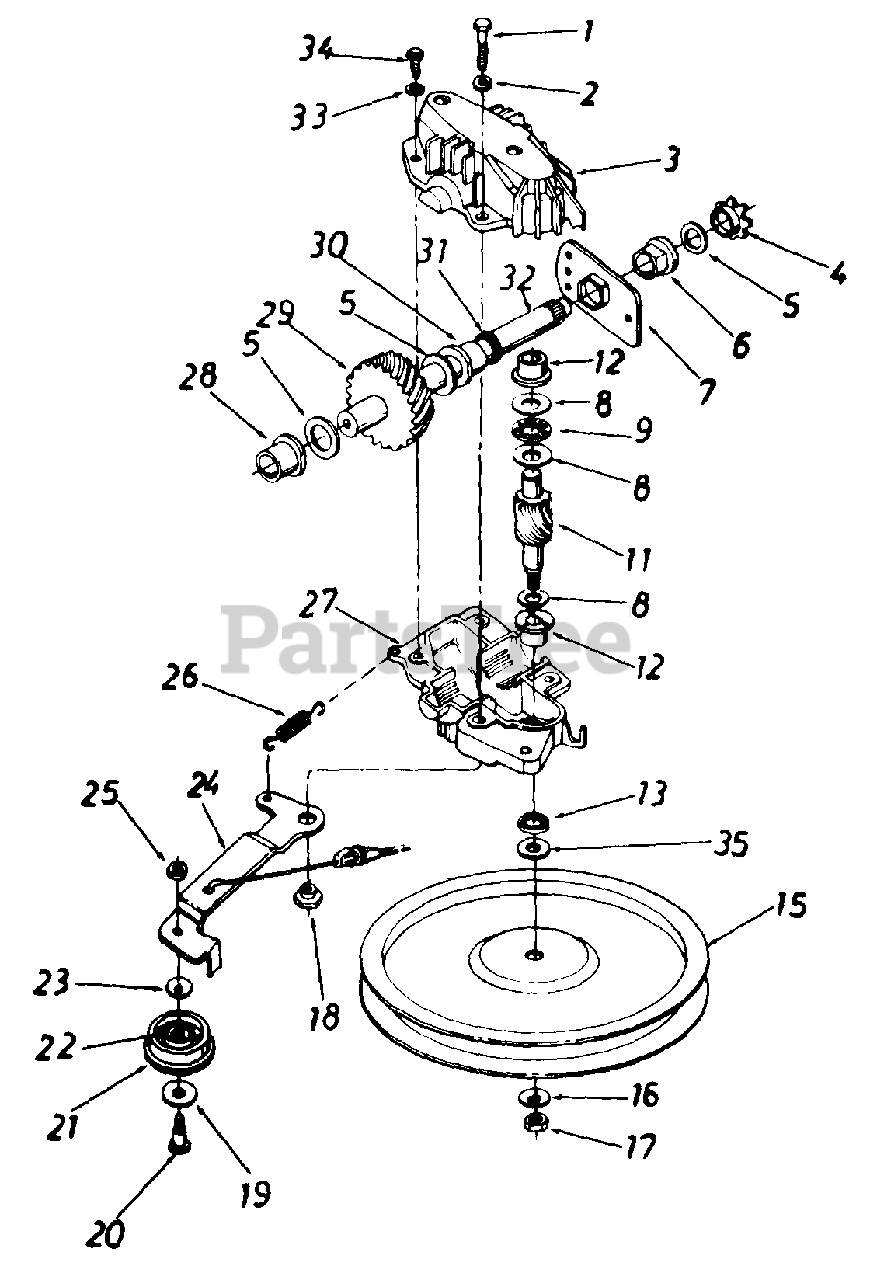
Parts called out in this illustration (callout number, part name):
1	Hex Bolt 1/4-20 x 1.25" Lg. w/Patch
2	L-Wash. 1/4" l.D.
3	Upper Hsg. Half
4	#48 Sprocket 7 Tooth x 1/2 Pitch
5	Fl-Wash. 5/8" I.D. x .030
6	Hex Flange Brg. .631" I.D.
8	Thrust Wash. .382" I.D. x .70" O.D.
9	Thrust Bearing .375" I.D. x .812" O.D.
11	11 Tooth Pinion Shaft
12	Flange Bearing
15	Fl-Pulley 5.06" O.D.
16	Bell-Wash. .265" I.D. x .75"
17	Hex L-Nut 1/4-28 L.H. Thd.
18	Shld. Spacer .375" Dia. x .170
19	Fl-Wash. .390" I.D. x 1.0"
20	Shld. Bolt .375" Dia. x .40"
21	Fl-Idler Plastic 1.50" Dia.
22	Needle Brg. .375" x .31
23	Bell-Wash. .265" I.D. x .75"
24	Idler Brk't. Ass'y.
25	Hex Patch L-Nut 1/4-28 Thd.
26	Extension Spring 1.12" Lg.
27	Lower Hsg. Half
28	Flange Bearing .566 Dia.
29	33 Tooth Helical Gear
30	Flange Bearing .629 Dia.
31	Oil Seal .625 Dia.
32	Gear Sprocket Shaft
33	L-Wash. #10 I.D.
34	Hex B-Tap Scr. #10 x .62"
35	Hex Washer .26" x .88"
717-04178	Transmission Comp.
